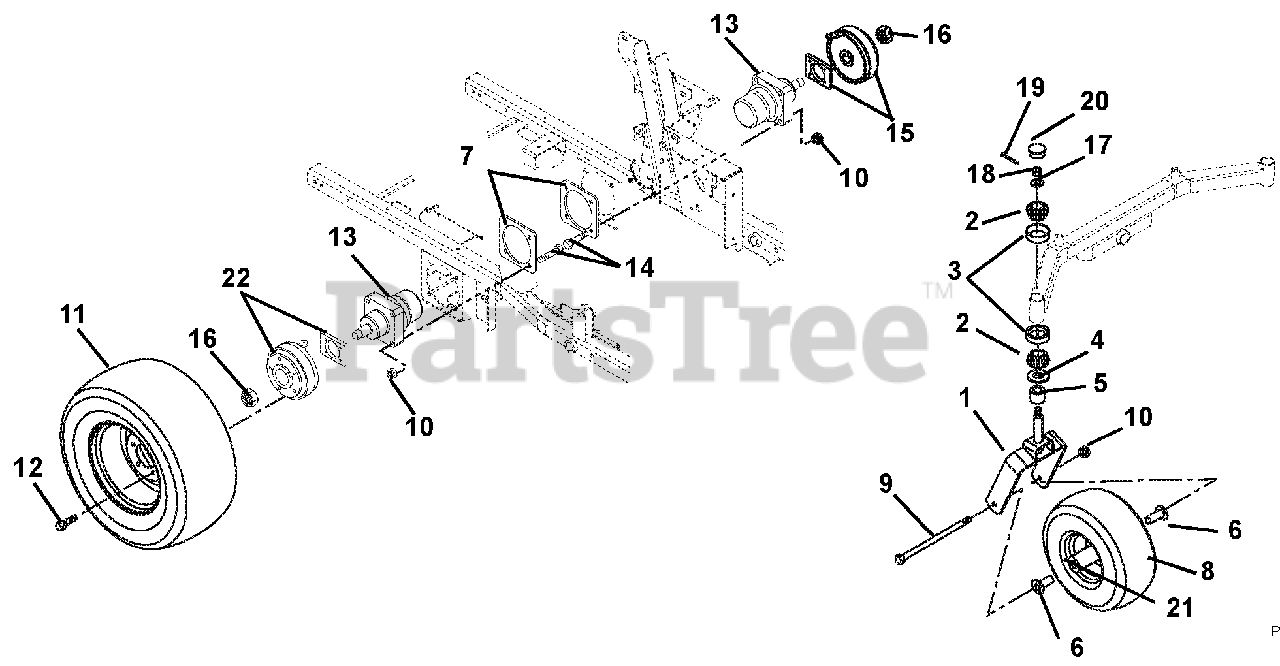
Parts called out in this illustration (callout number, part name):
1	Fork, Front
2	Bearing, Cone w/ Grease
3	Bearing, Cup 1.980 x .420
4	Bearing Seal 1.5 x 2 x .18
5	Spacer, PM, 1.03 I.D. x 1.5 O.D. x .375
6	Spacer, Wheel
7	Plate, Motor Support
8	Wheel/Tire Assembly
9	Bolt, Hex .50-13 x 9.00 Grade 5
10	Nut-Locking-Top-Flange .50-13
11	Tire/Wheel Assembly 24 x 12-12
12	Bolt, Lug .50-20 x 1.38 Grade 8, 60 Degree
13	Hydraulic Wheel Motor (includes 16)
14	Bolt, Wheel Motor .50-13 x 2.75
15	Brake, Right Hand Park
16	Nut, Lock Jam Patch (Included with 13)
17	Washer, Flat Steel .755 x 1.375 x .062
18	Nut, Slotted .75-16
19	Pin, Cotter .16 x 1.00
20	Cap, Dust
21	Bearing, 25mm I.D. x 52mm OD x 15mm
22	Brake, Left Hand Park
